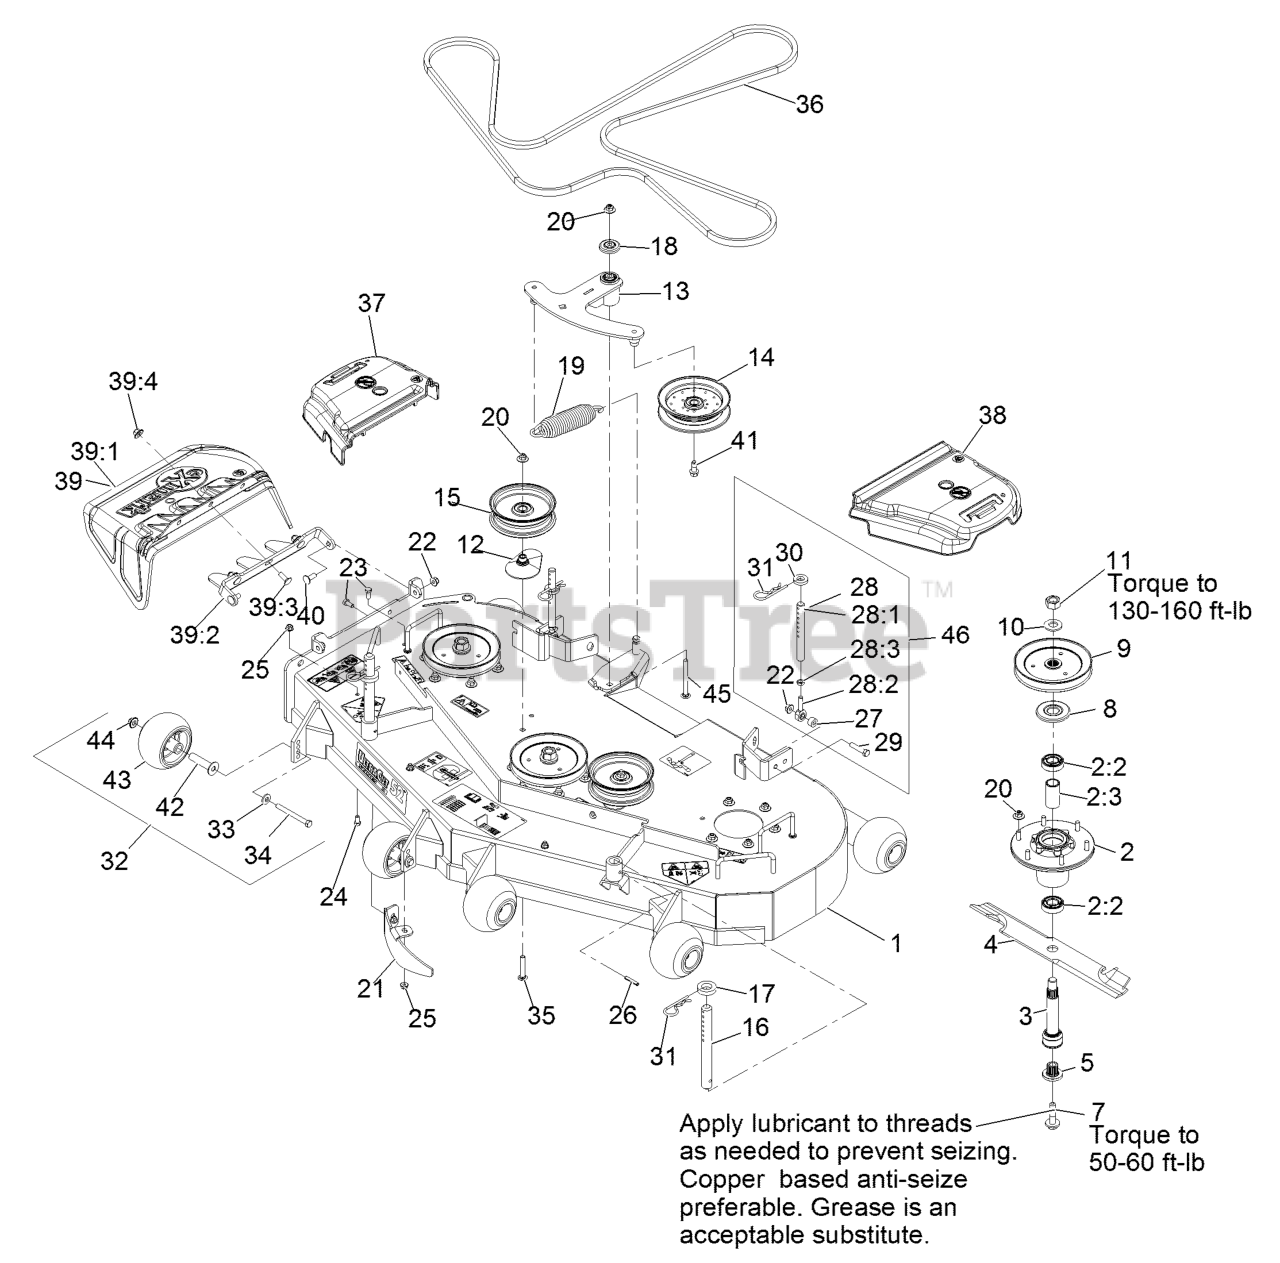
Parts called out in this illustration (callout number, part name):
1	ASM, DECK W/ DECALS, 52"
2	ASM-CUTTER HSG WITH BEARINGS
2:2	BEARING-BALL
2:3	SPACER-BEARING
3	ASM-SPINDLE AND SEAL
5	BUSHING,SPLINED
7	SCREW,SEMS 1/2-20 X 2.19
8	GUARD,BEARING TOP .989
9	SHEAVE,BLADE DRIVE 6.50
11	NUT-HEX
12	SPACER-PULLEY
13	ASM, DECK IDLER
15	IDLER-PULLEY, FLAT
16	ROD,DECK SUPPORT
17	SPACER-DECK SUPPORT
18	GUARD-TOP
19	SPRING-EXTENSION
20	Nut-Nyloc 3/8-16 Flg
21	BAFFLE, DOGLEG
22	NUT-HF, NI
23	SCREW-HH
24	SCREW-HH
25	NUT-HF, NI
28:1	LINK,SUPPORT
28:2	BALLJOINT
28:3	NUT-HJ
29	SCREW-HH
31	PIN,HAIR COTTER
32	KIT, ANTI-SCALP ROLLER
33	WASHER-BELLEVILLE
34	SCREW-HH 3/8-16 X 3 3/4 GR 8
35	BOLT-CARR, SHORT NECK
36	BELT, DECK
37	COVER-BELT, RH
38	COVER-BELT, LH
39	ASM, DISCHARGE CHUTE
39:1	CHUTE,DISCHARGE
39:2	BRACKET, DISCHARGE CHUTE
39:3	SCREW-CARR
39:4	Nut-Nyloc 3/8-16 Flg
40	SCREW-CARR
41	SCREW-HFH
42	AXLE, ROLLER
43	ROLLER-SCALP, ANTI
44	Nut-Nyloc 3/8-16 Flg
45	SCREW-CARR
46	KIT,SUPPORT LINK W/PIN
